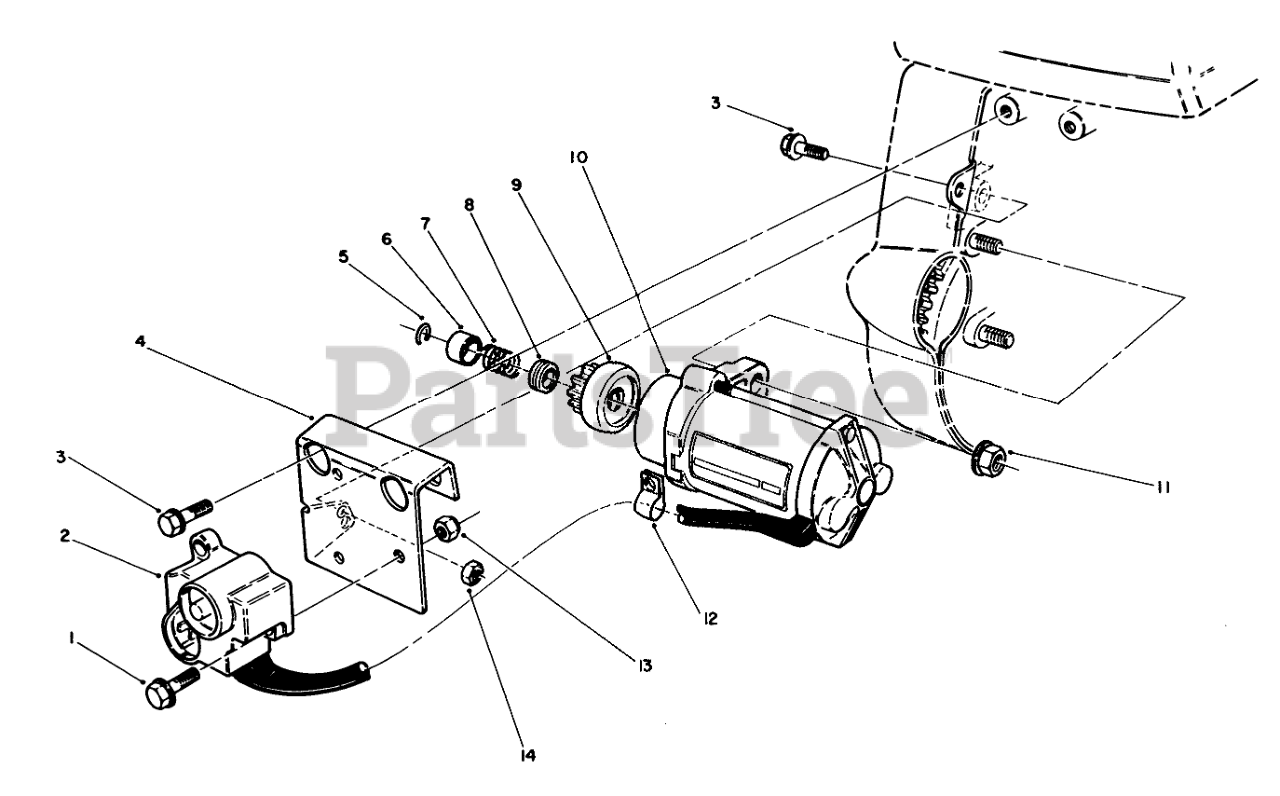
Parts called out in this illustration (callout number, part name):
2	Starter Switch Box
3	M6 X 1 HEX HD CAPSCRW
4	Bracket-Starter Switch
5	Retaining Ring
6	Pinion Stop
7	Spring
8	Spacer
9	Drive Assembly
12	CLAMP
13	NUT-LOCK, NI
14	Flange Nut
